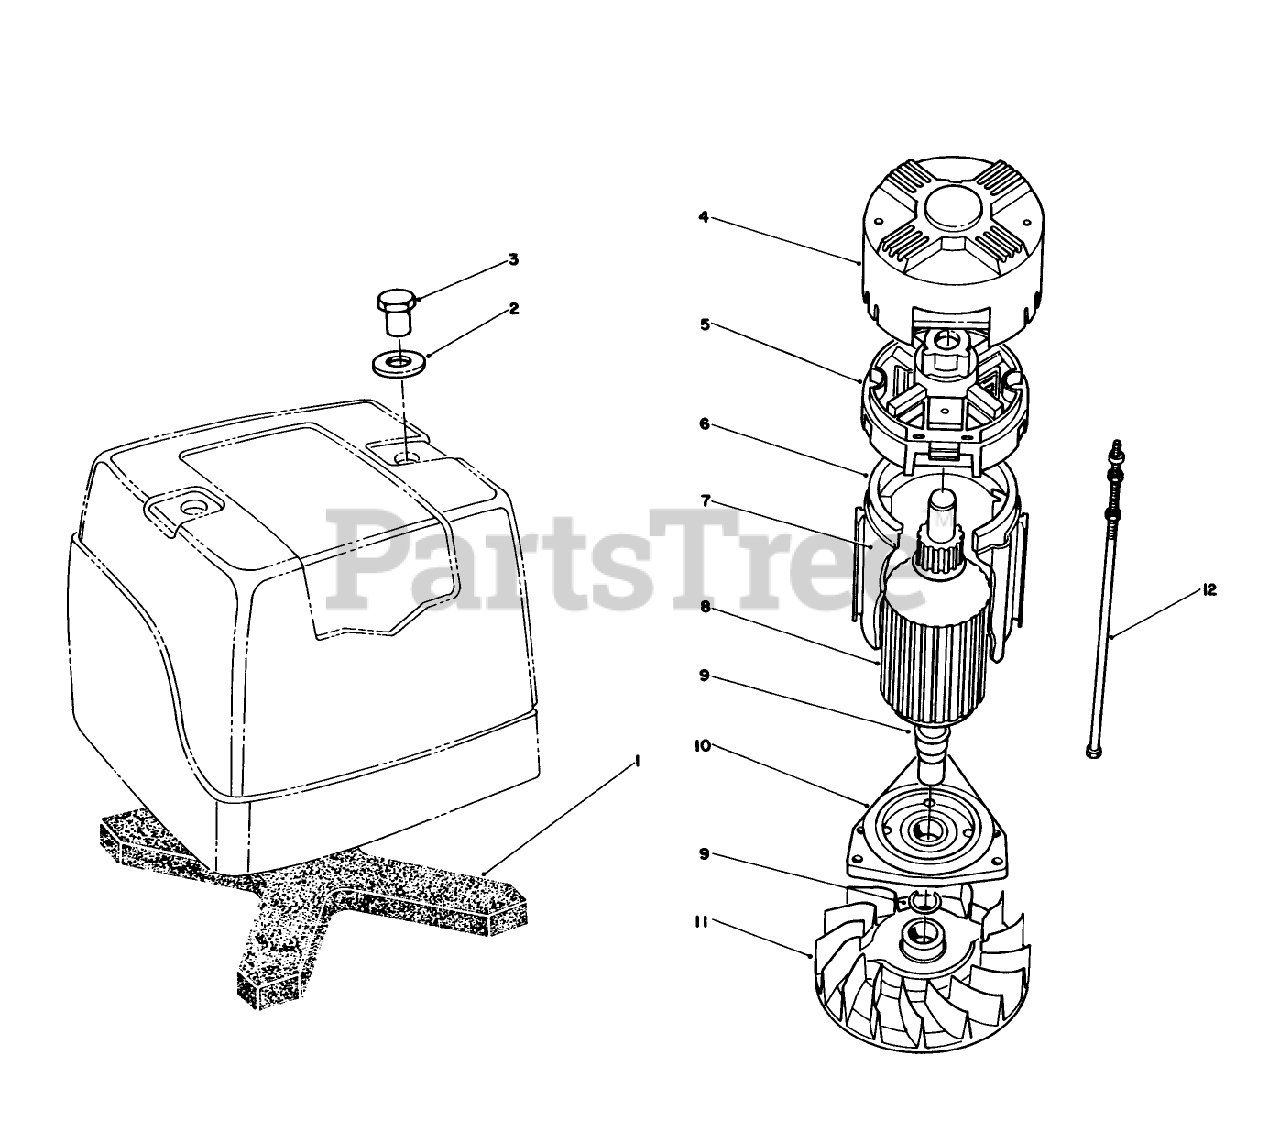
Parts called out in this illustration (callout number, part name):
1	Filter
2	Washer
3	Nut-Hex
4	End Cap-Brush
5	Brush Box Group (Includes: 490834 Brush Pin Group)
6	Housing Assembly
7	Insulator Group-Housing
8	Armature Group
9	Ring-Retaining
10	Spacer
12	Bolt-Thru (Includes Two Sets)
